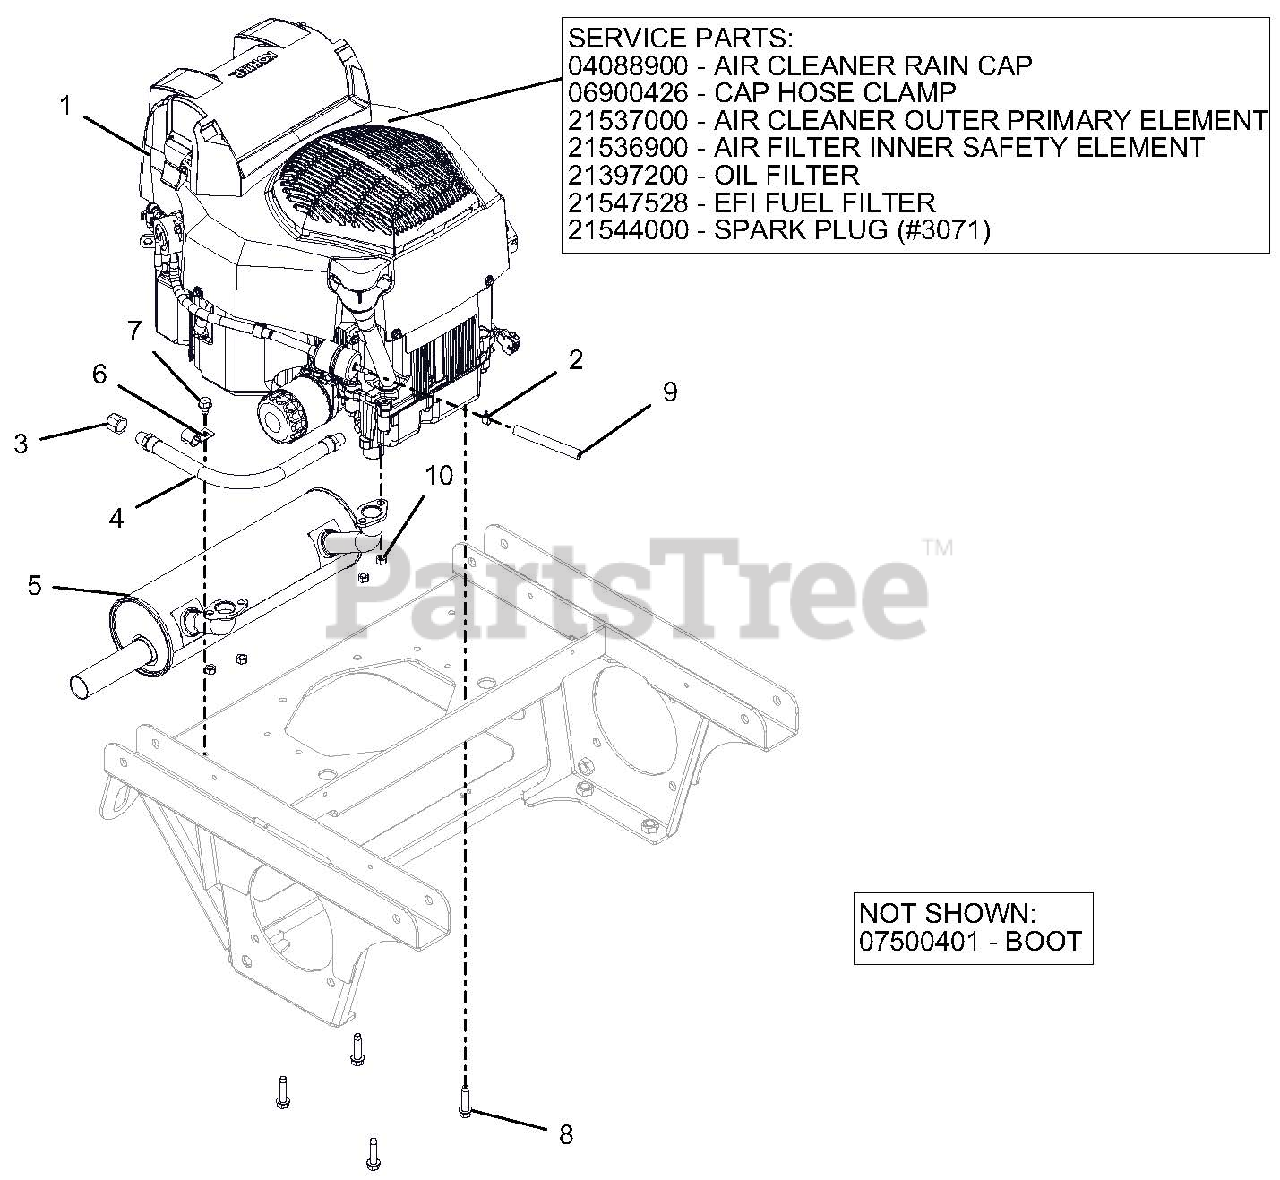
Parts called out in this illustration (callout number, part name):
1	ENGINE, KOHLER ZT740 CONFIDANT
1	AIR CLEANER RAIN CAP
1	CAP HOSE CLAMP
1	AIR CLEANER OUTER PRIMARY ELEMENT
1	AIR FILTER INNER SAFETY ELEMENT
1	OIL FILTER
1	EFI FUEL FILTER
1	SPARK PLUG
2	CLAMP, FUEL LINE
3	PIPE, CAP 3/8 NPT FEMALE
4	HOSE, HYD .38-11-OK M6N0-M6N0
5	MUFFLER, KOHLER CONFIDANT
7	SCR-TAP .38-16X.50 HWH TR YWZ
8	SCR-TAP .38-16X1.50 HWH TR YZ
9	.25 LOW-PERM GAS HOSE 42.00" LG - VALVE TO ENGINE
10	NUT-LK-TOP M8-1.25 YWZC
